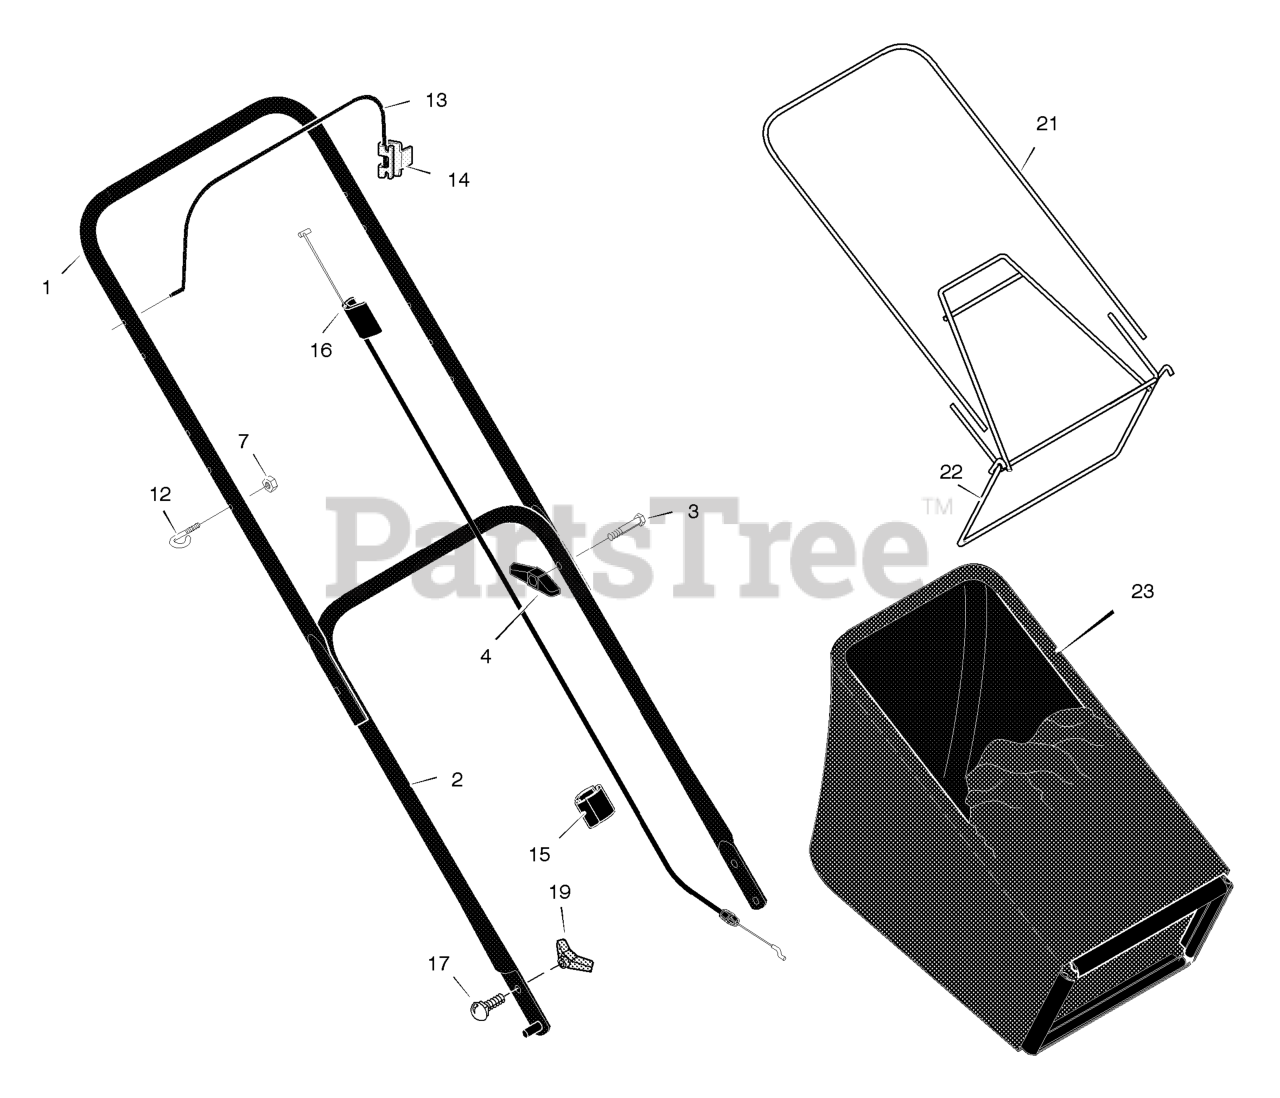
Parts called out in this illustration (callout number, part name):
1	Handle, Upper (Black)
2	Handle, Lower (Black)
4	Knob, Plastic
7	Locknut
12	Guide, Rope
13	Lever, Engine Stop
14	Bracket, Stop Lever
15	Clip, Cable
16	Engine Stop Cable
17	Bolt, Carriage
19	Knob, Plastic
21	Frame Top
22	Frame Assembly
23	Bag, Cloth
